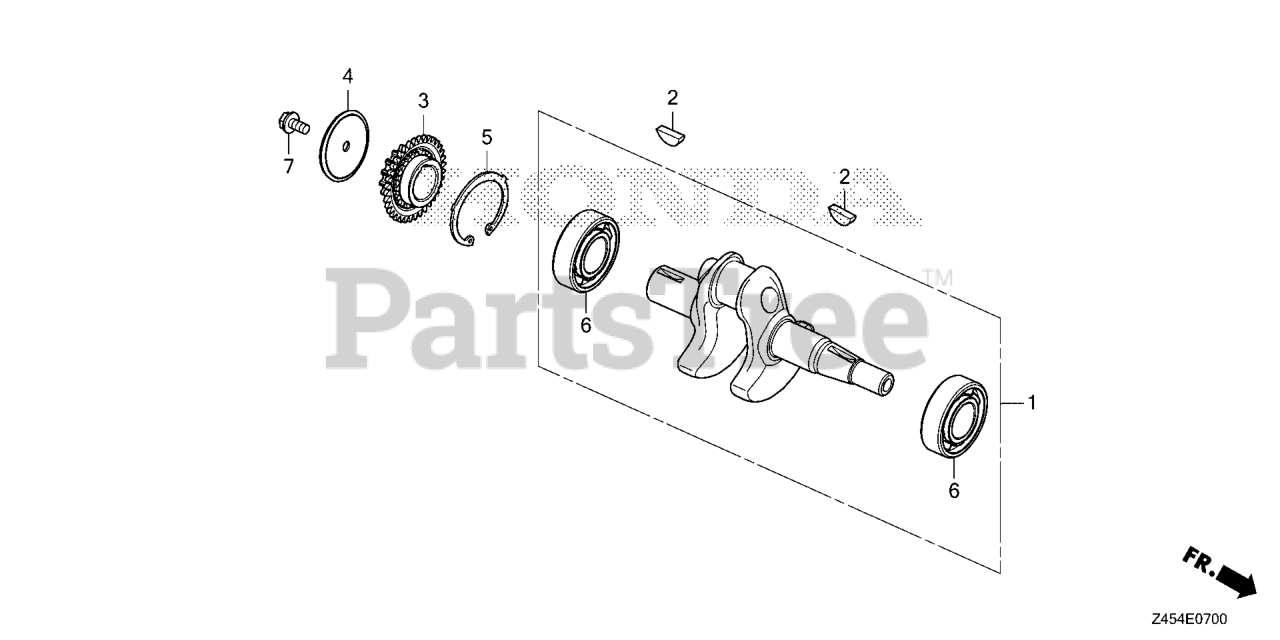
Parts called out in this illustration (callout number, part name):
1	CRANKSHAFT COMP
2	KEY, SPECIAL WOODRUFF (25X18)
3	PULLEY COMP
4	GUIDE, T/B DRIVE
5	CIRCLIP, IN (47)
6	BEARING (6204)
7	BOLT, FLANGE (6X12) Use up to Engine SN 1543277.
